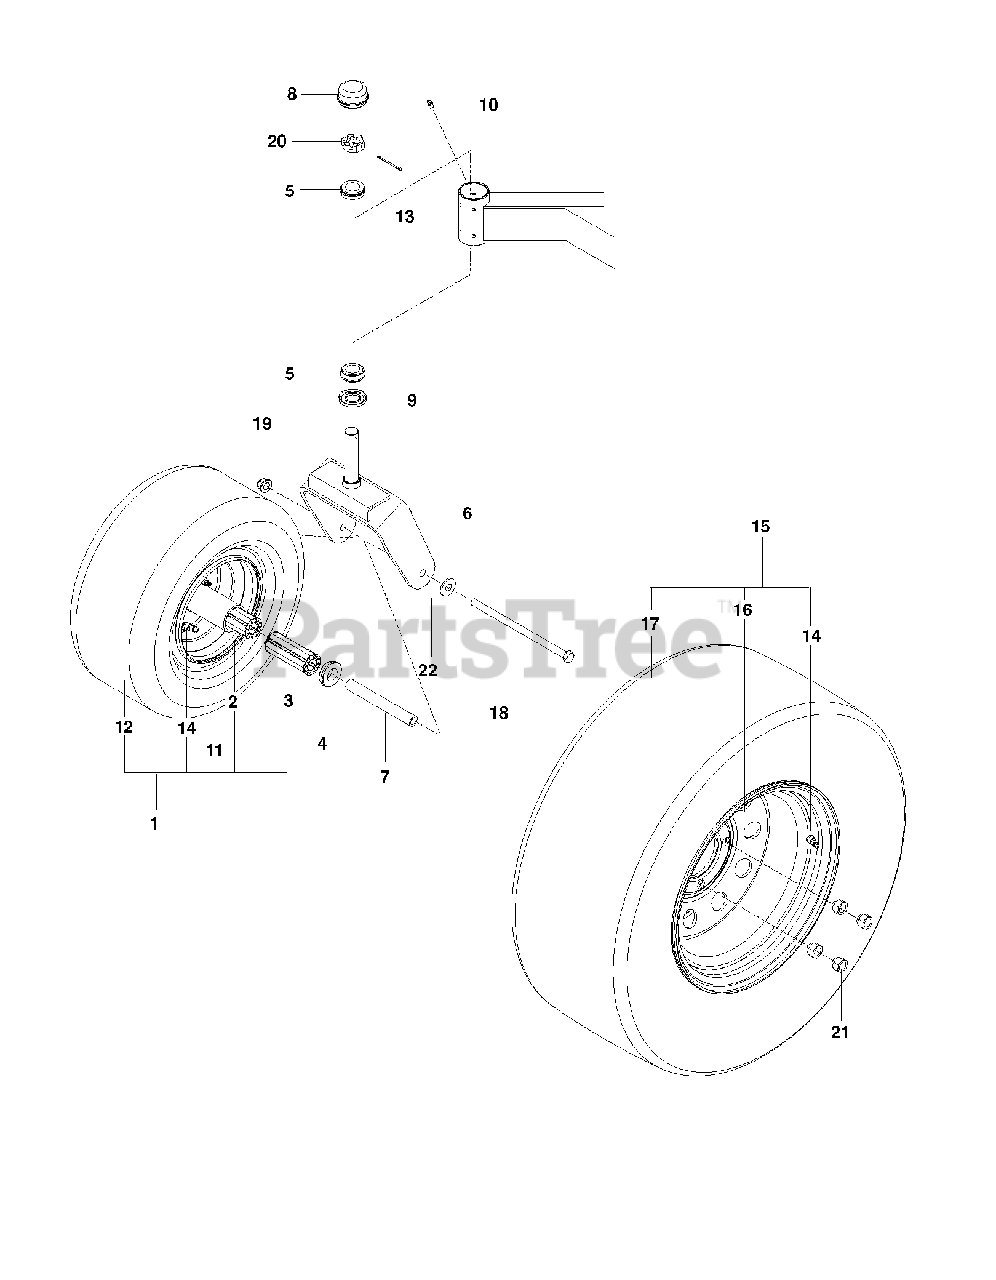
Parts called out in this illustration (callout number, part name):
1	ASM, TIRE
2	WHEEL, 6 X 4.50
3	ROLLER BEARING-CAGED 3 1/4'
4	BEARING RETAINER
5	TAPERED ROLLER BRG
6	YOKE, CASTER, BLUE
7	SPACER, PIVOT
8	GREASE CAP
11	ZERK
12	TIRE, 13 X 6.50 - 6, 4 PLY
14	VALVE STEM TR-412
15	ASSEMBLY, TIRE 23 X 9.20-12
16	RIM, 12 X 7, 1" NEG OFFSET
17	TIRE, 23 X 9.50-12
18	HEX SCREW 1/2-13 X 9.5 GR5
19	NUT, 1/2-13 HEX FLG NYLOC ZD
20	NUT 1"C HEX SLOTTED
21	LUG NUT 1/2F
22	WASH USS FLAT 1/2
